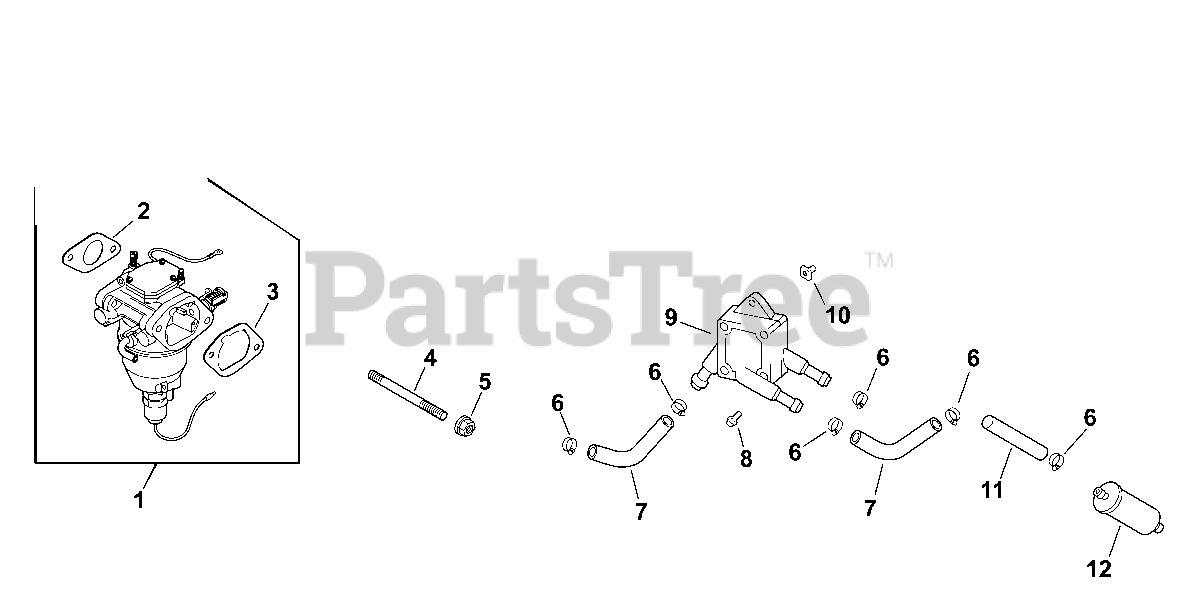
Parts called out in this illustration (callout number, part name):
1	KIT, CARBURETOR W/GASKETS
2	GASKET, CARBURETOR
3	GASKET, AIR CLEANER BASE
4	STUD,M6X1.0X96
5	NUT, FLG M6X1.0
6	LINE FLEXBLE FUEL (3.5" x.25") -USE 25 1
7	CLAMP, HOSE (KM)-USE 25 237 31-S
8	SCREW, TAP M6X1.7X18
9	PUMP, FUEL
10	NUT, PLASTIC (KM)-USE 25 100 37-S
11	LINE, FLEXIBLE FUEL 10.92"-USE 24 353 12
